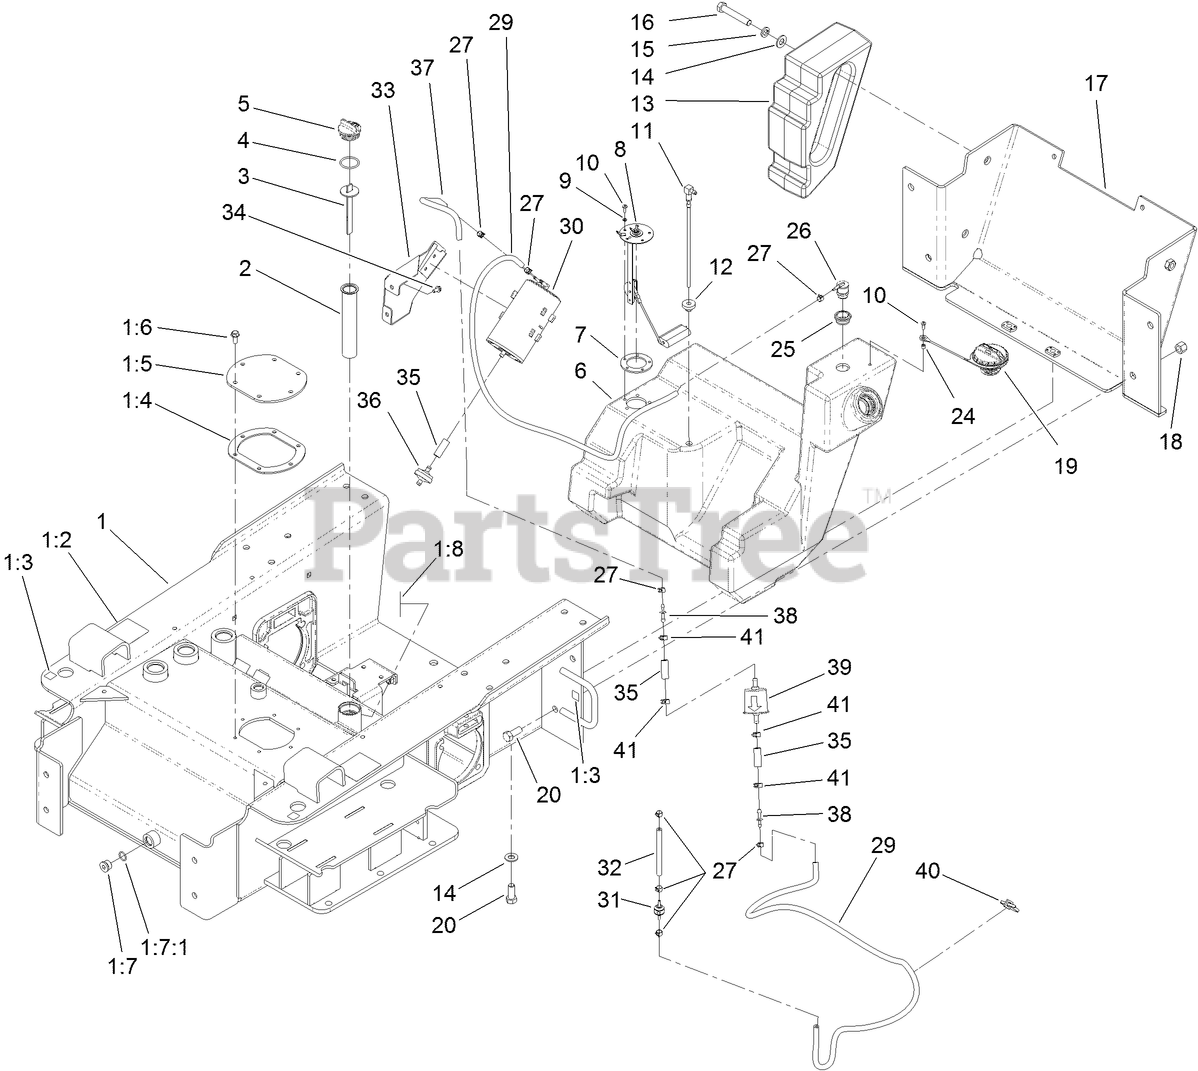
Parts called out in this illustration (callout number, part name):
1	CHASSIS ASM
1:2	DECAL-WARNING
1:3	DECAL-POINT, LIFT
1:4	GASKET-COVER, ACCESS
1:5	COVER-TANK
1:6	SCREW
1:7	PLUG-HEX
1:7:1	O-RING
1:8	DECAL-OIL, HYD
2	FILTER-SCREEN
3	DIPSTICK-OIL
4	O-RING
5	PLUG-PLASTIC
6	TANK-FUEL
7	GASKET-SENDER, FUEL
8	SENDER-FUEL
9	WASHER-LOCK
10	SCREW-PPH
11	PIPE-STAND
12	BUSHING
13	COUNTERWEIGHT-REAR
14	WASHER-FLAT
15	WASHER-LOCK
16	SCREW-HH
17	COVER-REAR
18	NUT-LOCK, NI
19	CAP-FUEL
20	SCREW-HH
24	SPACER
25	GROMMET
26	VALVE-ROLLOVER
27	CLAMP-HOSE
29	HOSE-FUEL
30	CANISTER-CARBON
31	VALVE-CHECK, VACUUM
32	HOSE-FUEL
33	HOLDER-CANISTER
34	SCREW-HWH
35	HOSE-FUEL
36	FILTER-FUEL, INLINE
37	HOSE-FUEL
38	FITTING-STRAIGHT
39	FILTER-FUEL
40	TIE-CABLE
41	CLAMP-HOSE
